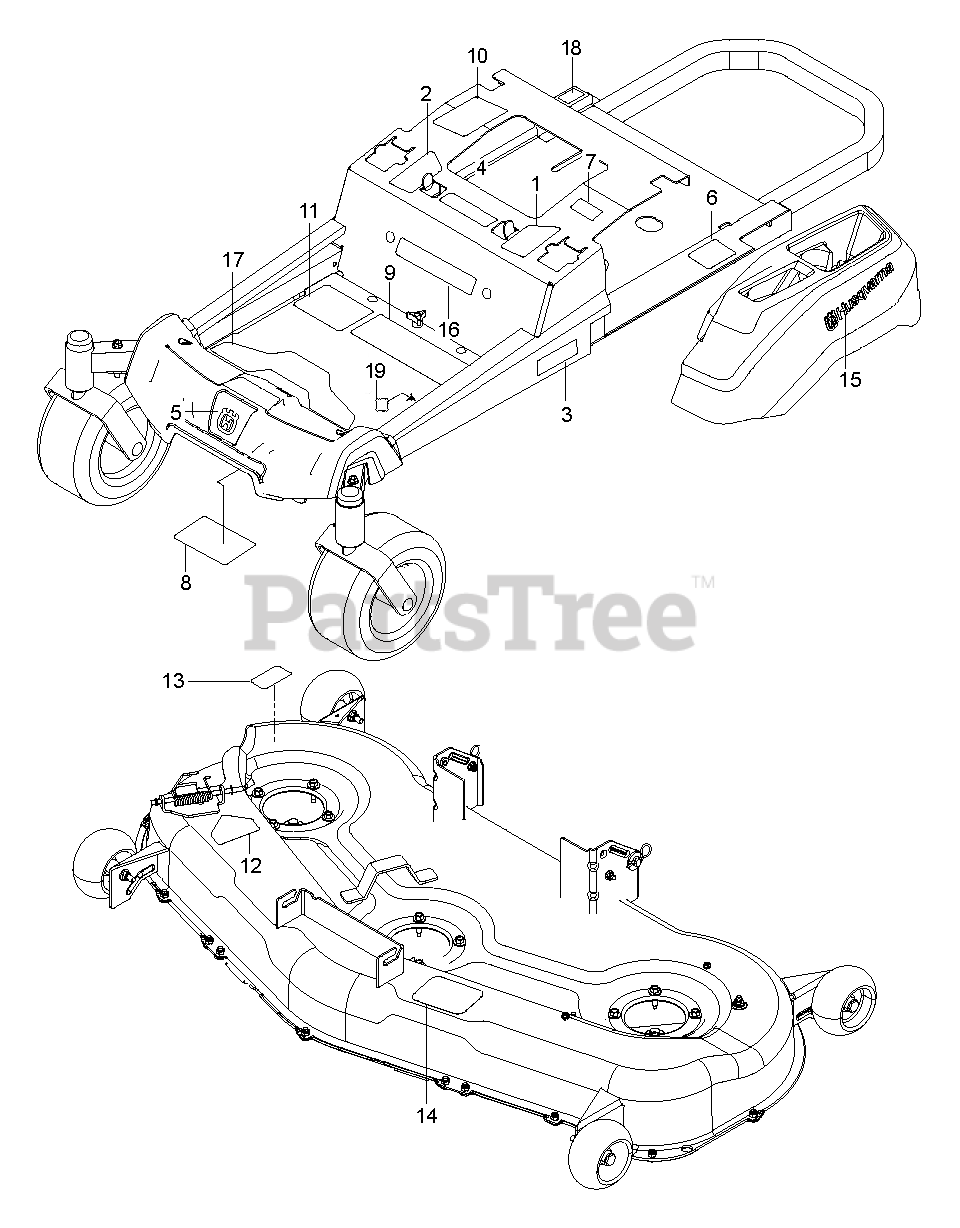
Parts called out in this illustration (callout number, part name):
1	DECAL.ZTR.RZ.THRTL/PRKBRK.V2.L
2	DECAL.ZTR.RZ.THRTL/PRKBRK.V2.R
3	DECAL.ZTR.SIDE.RAIL.GRAPHIC
4	EURO DECAL-BATTERY WARNIN6
5	DECAL.BADGE.55MM.CROWNH.HUSQ
6	DECAL, DO NOT TOW
7	DECAL, EXITING MOWER
8	DECAL, SERVICE
9	DECAL ZTR WARNING DECAL DECAL.
9	DECAL.ZTR.WARNING.SMARTIGNITIN
10	DECAL.WARNING.CUST.RESP.E85.
11	DECAL.ZTR.STRTNGINST.REMOTECHK
11	DECAL.ZTR.STARTINSTRCT.CHOKE15
12	DECAL, DECK DEFLECTOR, WARNING
13	DECAL.DECK.6MIL./DEF.SHLD.WARN
14	DECAL, BELT ROUTING
15	DECAL.HUSQVARNA.210MM
16	DECAL ZTR BRAND GRAPHIC DECAL.
17	PAD.RZ.FOOTREST.PLATE
18	DECAL CERTIFICATION DECAL EMCC
19	DECAL.80.DBA.AUSTRALIA
